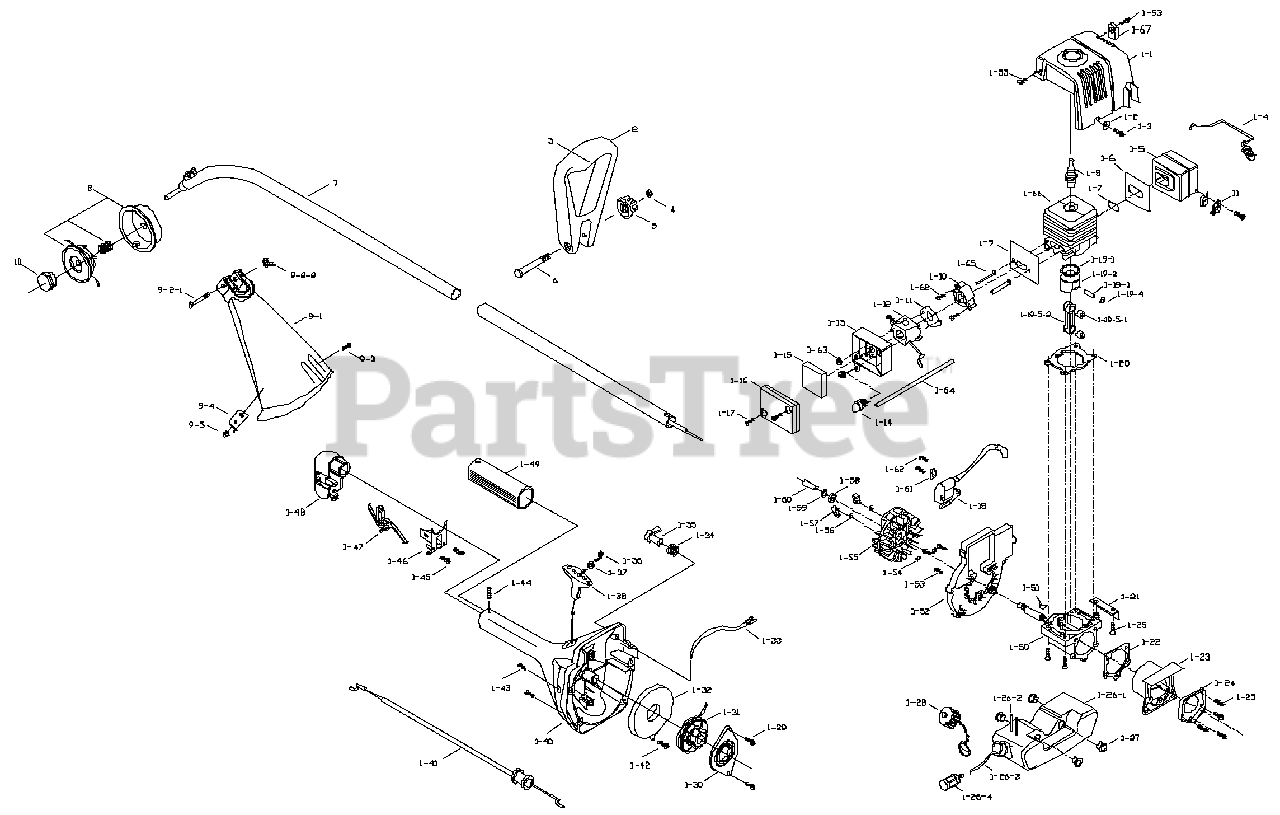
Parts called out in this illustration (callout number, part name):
1	ENG ASS'Y
1-4	SPRING, MUFFLER
1-5	KIT, MUFFLER
1-6	GASKET, MUFFLER
1-7	GASKET
1-8	SPARK PLUG
1-9	GASKET, MUFFLER
1-10	MANIFOLD, CARBURETOR
1-11	GASKET, CARBURETOR
1-12	CARBURETOR ASS'Y
1-13	BOX, AIR
1-14	PRIMER, REMOTE
1-15	FILTER, AIR
1-16	COVER, AIR CLEANER
1-18	IGNITION ASSEMBLY
1-19	PISTON/CONNECTING BAR ASS'Y
1-19-1	RING, PISTON
1-19-2	KIT, PISTON
1-19-3	PIN, C,SHAFT PISTON
1-19-4	RING, RETAINING
1-19-5	ROD, CONNECTING ASS'Y
1-19-5-2	ROD, CONNECTING
1-20	GASKET, CYLINDER
1-21	SHIELD, MUFFLER
1-22	GASKET
1-23	PLUG, C'CASE
1-24	PLATE, C'CASE, COATED FINISH
1-25	SCREW
1-26	TANK ASS'Y FUEL
1-26-1	KIT, FUEL TANK
1-26-3	HOSE
1-26-4	PICKUP, FUEL
1-27	ISOLATOR
1-28	CAP, FUEL TANK
1-29	SCREW
1-30	RETAINER, PULLEY
1-31	DRUM/ ROPE ASS'Y
1-32	PACKAGE, SPRING ASS'Y
1-33	WIRE ASS'Y, SWITCH
1-34	SPRING, BULLON STOP
1-35	BULLON, STOP
1-36	ROPE, STARTER
1-37	WASHER, NYLON
1-38	HANDLE, STARTER
1-39	GUIDE, ROPE
1-40	STARTER HOUSING
1-41	THROTTLE CABLE
1-42	SCREW, SPRING RETAINER
1-44	SCREW
1-46	COVER SWITCH HOUSING
1-47	TRIGGER, THROTTLE
1-48	TRIGGER HOUSING
1-50	C'CASE/C'SHAFT ASSY
1-51	KEY, FLYWHEEL
1-52	SHIELD MUFFLER
1-53	SCREW
1-54	RING, RETAINER
1-55	FLYWHEEL
1-57	PAWL KIT, STARTER
1-61	TERMINAL TAB
1-62	SCREW
1-64	HOSE, FUEL RETURN
1-65	SCREW
1-66	KIT, CYLINDER/GASKET
1-67	WASHER, PLASTIC
2	KIT, HANDLE
3	COVER, KIT
5	KNOB
6	SCREW
7	SHAFT ASS'Y
8	KIT, STRINGHEAD
9	SHIELD ASS'Y
9-2	SCREW/NUT ASS'Y
9-2-1	SCREW
9-2-2	NUT
9-3	SCREW
9-4	KIT, KNIFE
10	KNOB ASS'Y
11	SCREEN, SPARK ARRESTER
